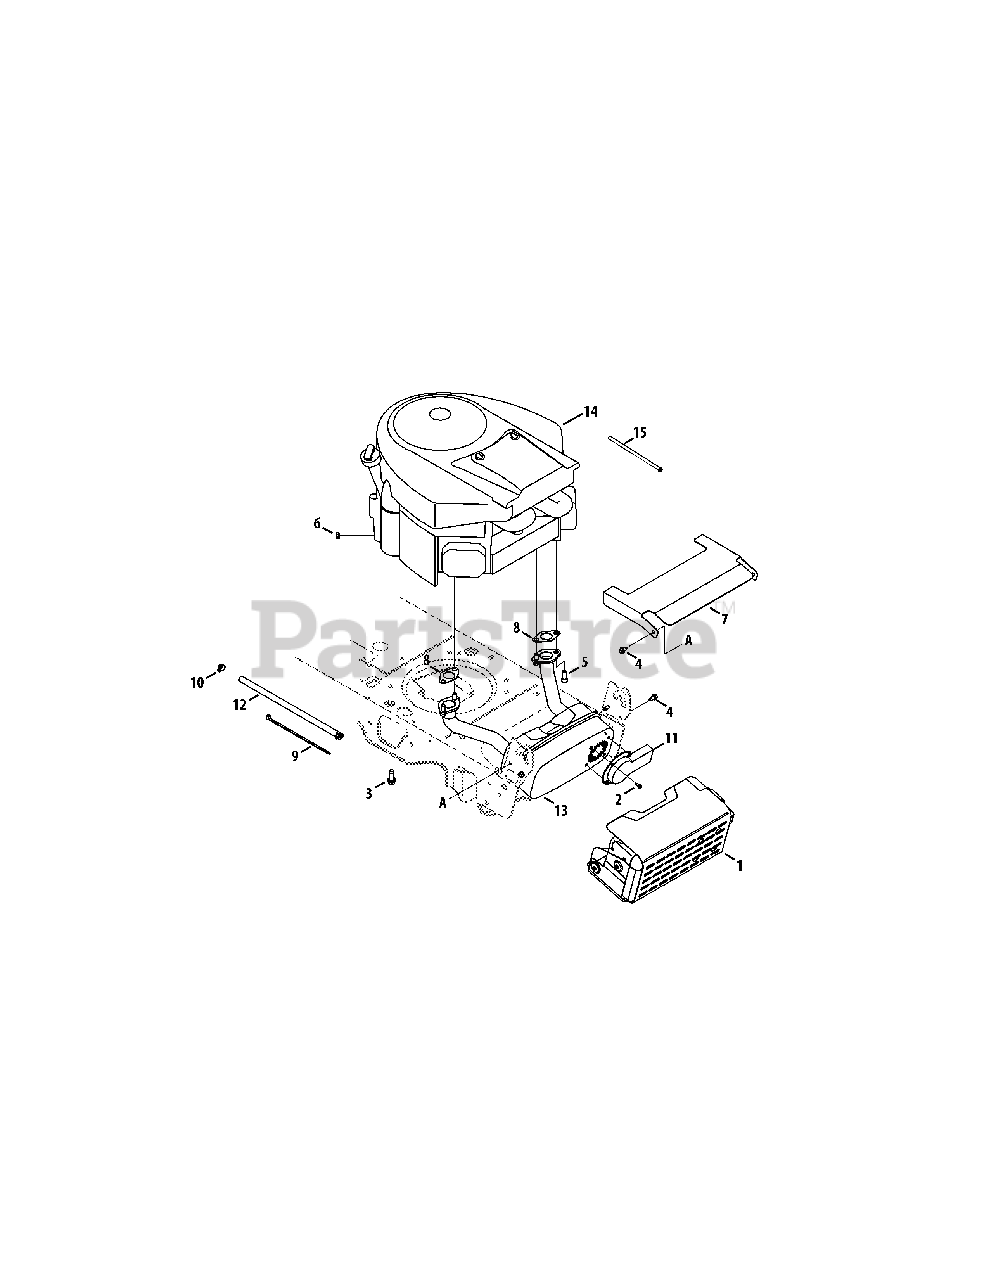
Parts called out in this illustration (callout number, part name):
1	Mulffler Shield Assembly
2	Screw, Indented Washer, #8-18:0.500
3	Taptite Screw, Indented Washer, 3/8-16:1.000
4	Taptite Screw, Indented Washer, 1/4-20:0.500
5	Socket Head Screw, 5/16-18:.750
6	Sems Nut, 1/4-20
7	Heat Shield
8	Exhaust Gasket
9	Cable Tie, 3/16 X .05 X 7.4
10	Hose Clamp, .490 DIA.
11	Long Muffler Deflector
12	Fuel Hose
13	Muffler
14	Replacement Engine 44P777-2799-G1/G5
15	Vent Hose, 3/16 Red
